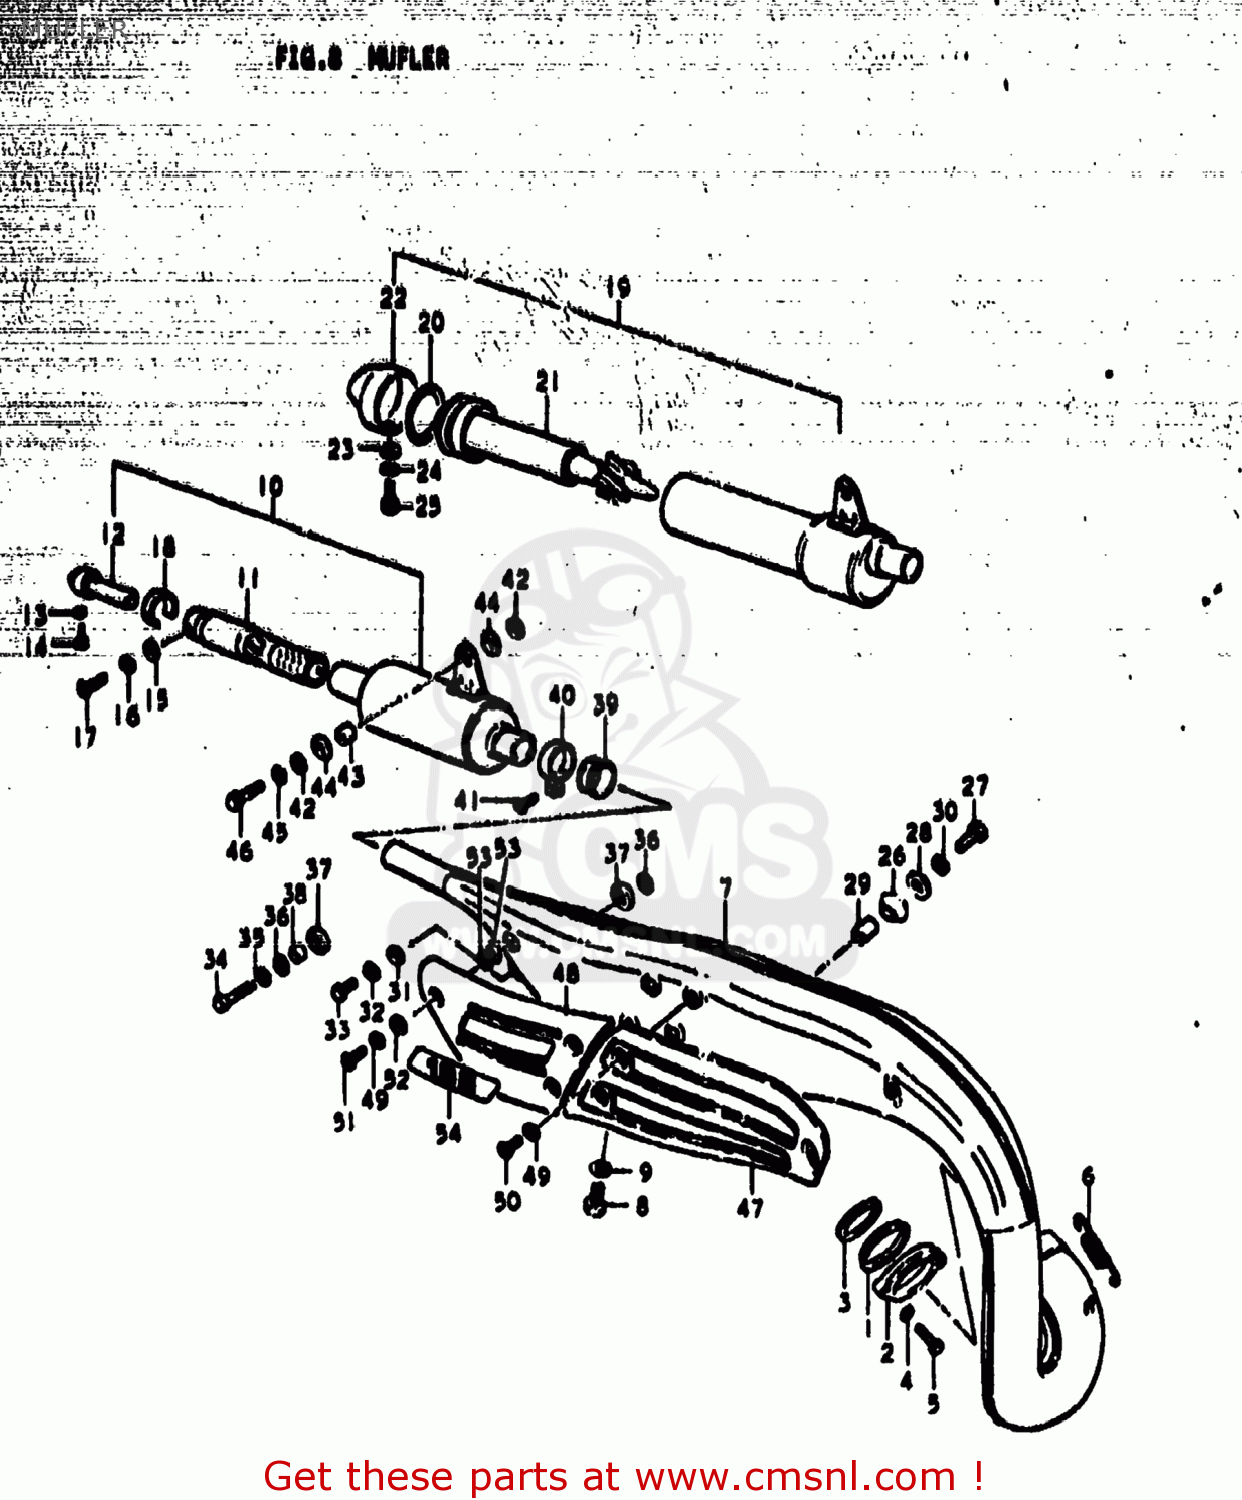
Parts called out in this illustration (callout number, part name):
1	GASKET,EXHAUST PIPE (NAS)
2	CLAMP,EXHAUST PIPE
3	CUSHION,EXHAUST PIPE
4	LOCK WASHER
5	BOLT
6	SPRING
7	BODY,MUFFLER
8	BOLT 10X9
9	GASKET(10X14X3.6) (NAS)
10	MUFFLER ASSEMBLY
11	ARRESTER,SPARK
12	TUBE,MUFFLER CLEAN OUT
13	LOCK WASHER
14	SCREW
15	WASHER
16	LOCK WASHER
17	SCREW(6X8)
18	BAND,SPARK ARRESTER
19	MUFFLER ASSEMBLY
20	O-RING (D:3.5 ID:54.4)
21	TUBE,MUFFLER CLEAN OUT
22	COVER,SECOND MUFFLER TAIL
23	WASHER
24	LOCK WASHER
25	SCREW(6X8)
26	DAMPER,MUFFLER,FR
27	BOLT
28	WASHER
29	SPACER
30	LOCK WASHER
31	WASHER
32	LOCK WASHER
33	BOLT
34	BOLT
35	LOCK WASHER
36	WASHER (8.2X20X1.6)
37	CUSHION
38	SPACER (8.6X13.8X9.8)
39	CONNECTOR,MUFFLER
40	CLAMP
41	SCREW
42	WASHER
43	SPACER
44	CUSHION
45	LOCK WASHER
46	BOLT
47	COVER,MUFFLER,FRONT
48	COVER,MUFFLER
49	LOCK WASHER
50	SCREW
51	SCREW 6X12
52	WASHER
53	GASKET 6.2X12X1.5 (MCA)
54	EMBLEM,MUFFLER COVER
